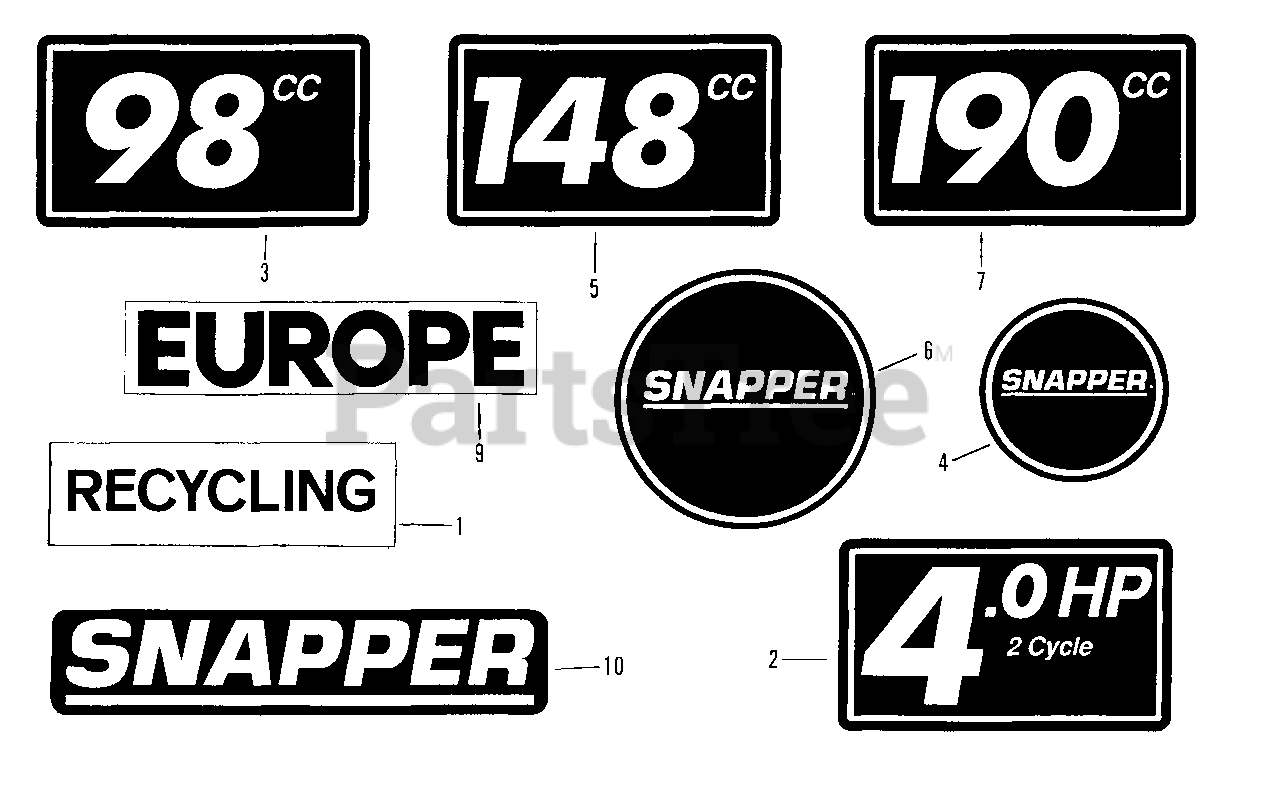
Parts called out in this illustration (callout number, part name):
1	DECAL, Recycling Mower
2	DECAL, Housing
3	DECAL, Housing
4	DECAL, Recoil
5	DECAL, Housing
6	DECAL, Recoil
7	DECAL, Housing
9	LABEL, EUROPE
10	LOGO, SNAPPER
